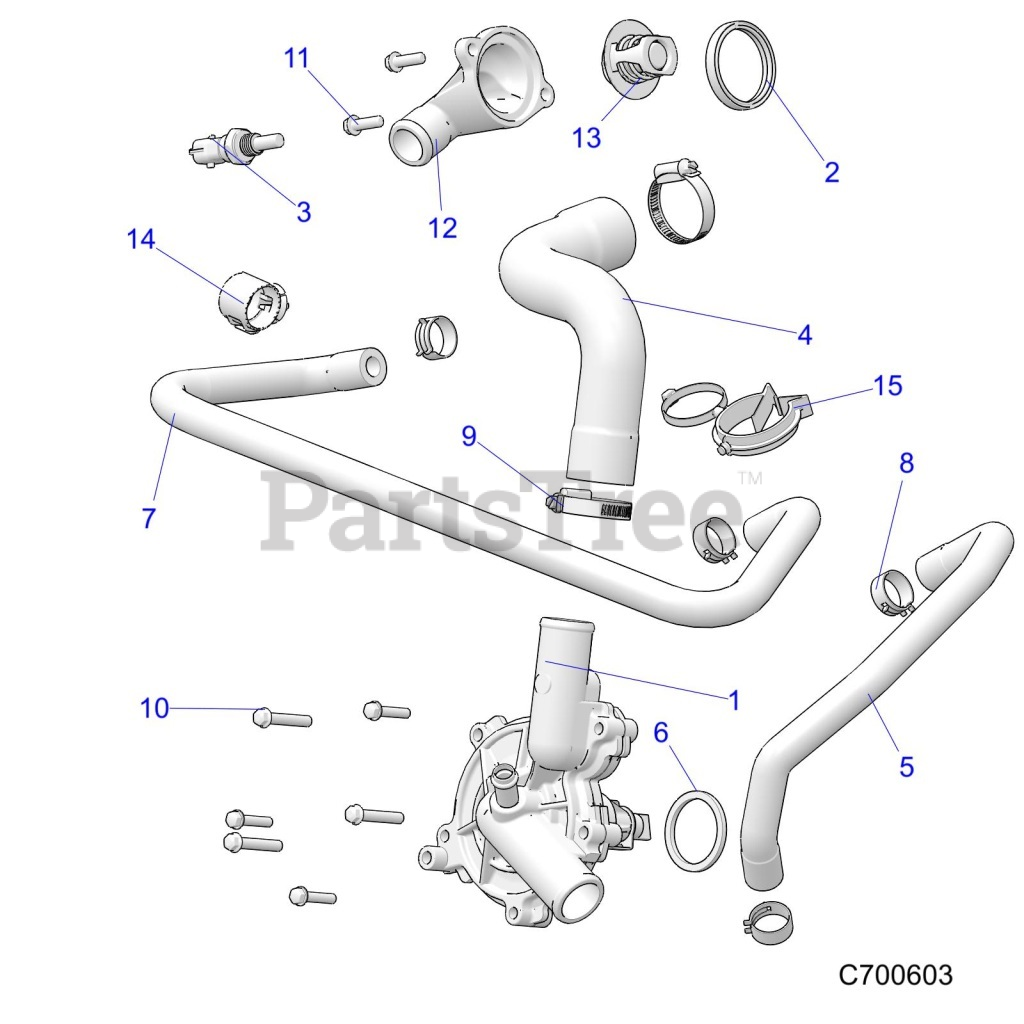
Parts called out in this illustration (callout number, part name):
1	ASM, WATERPUMP
2	SEAL-THERMOSTAT
3	SENSOR-THERMISTER
4	HOSE-WATERPUMP,OUT
5	HOSE-OIL COOLER OUT
6	FILTER, WP
7	HOSE-BYPASS LINE
8	CLAMP, HOSE, SPRING
9	CLAMP-HOSE(WORM DR)25-40MM
10	SCR-HXFL,M6X1.0X35,W/PATCHLOK
11	SCR-M6X20,HXFLG,0600214
12	COVER-THERMOSTAT
13	THERMOSTAT-44M FLANGE,180F
14	CLIP-HOSE
15	CLIP-CABLE,OMEGA,31-39MM
